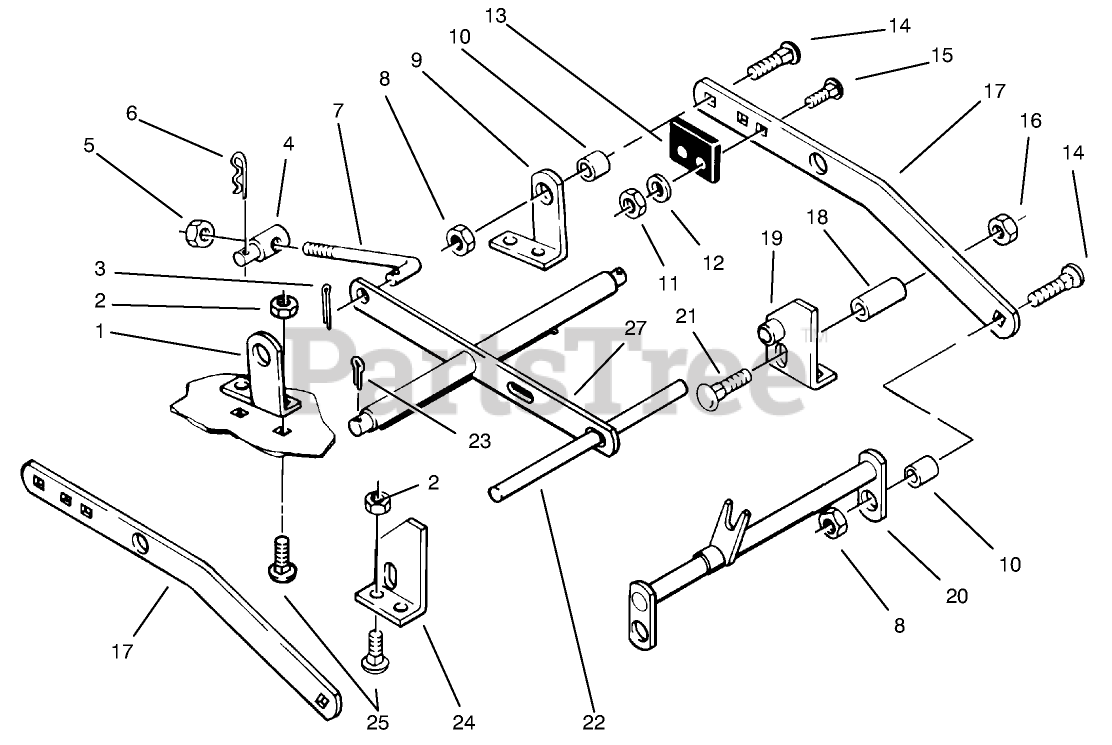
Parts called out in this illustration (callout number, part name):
1	RH BRKT-DECK REAR
2	NUT-LOCK, NI
3	PIN-COTTER
4	TRUNNION-LIFT
5	NUT-LOCK, NI
6	Hairpin
7	ROD-LEVEL ADJUST
9	LH BRKT-DECK REAR
10	SPACER
11	NUT-LOCK, NI
12	WASHER-FLAT
13	BUMPER
14	BOLT-CARR
15	SCREW-CARR
16	NUT-LOCK, NI
17	BAR DRAFT
19	WA BRACKET FT L
20	WA HITCH
21	BOLT-CARR
23	PIN-COTTER
24	WA BRACKET FT R
25	BOLT-CARR
27	LEVELER WA
